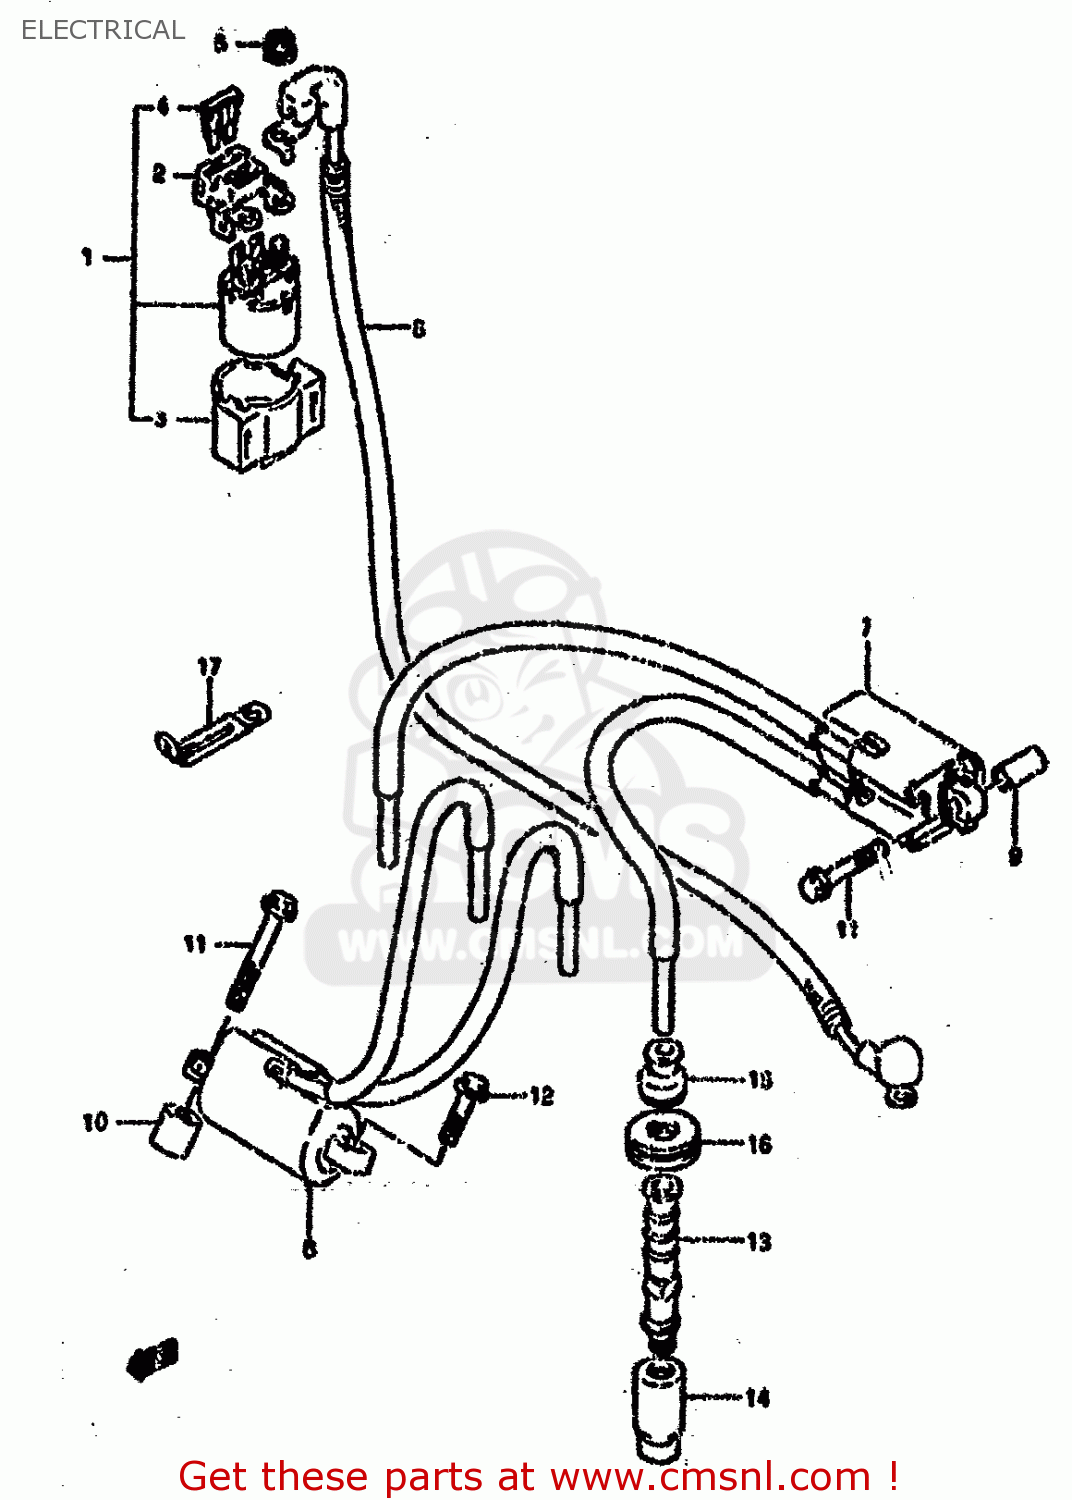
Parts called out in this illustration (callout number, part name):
1	RELAY ASSY,STARTING MOTOR
2	TERMINAL,RELAY
3	BRACKET,STARTING MOTOR RELAY
4	FUSE (30A)
5	NUT
6	WIRE,STARTER MOTOR LEAD
7	COIL ASSY,IGNITION
8	COIL ASSY,IGNITION
9	SPACER
10	SPACER,IGNITION COIL 1
11	BOLT
12	BOLT
13	CAP,SPARK PLUG
14	SEAL,SPARK PLUG
15	SEAL,HIGH TENSION CORD
16	COVER,SPARK PLUG CAP
17	CLAMP
